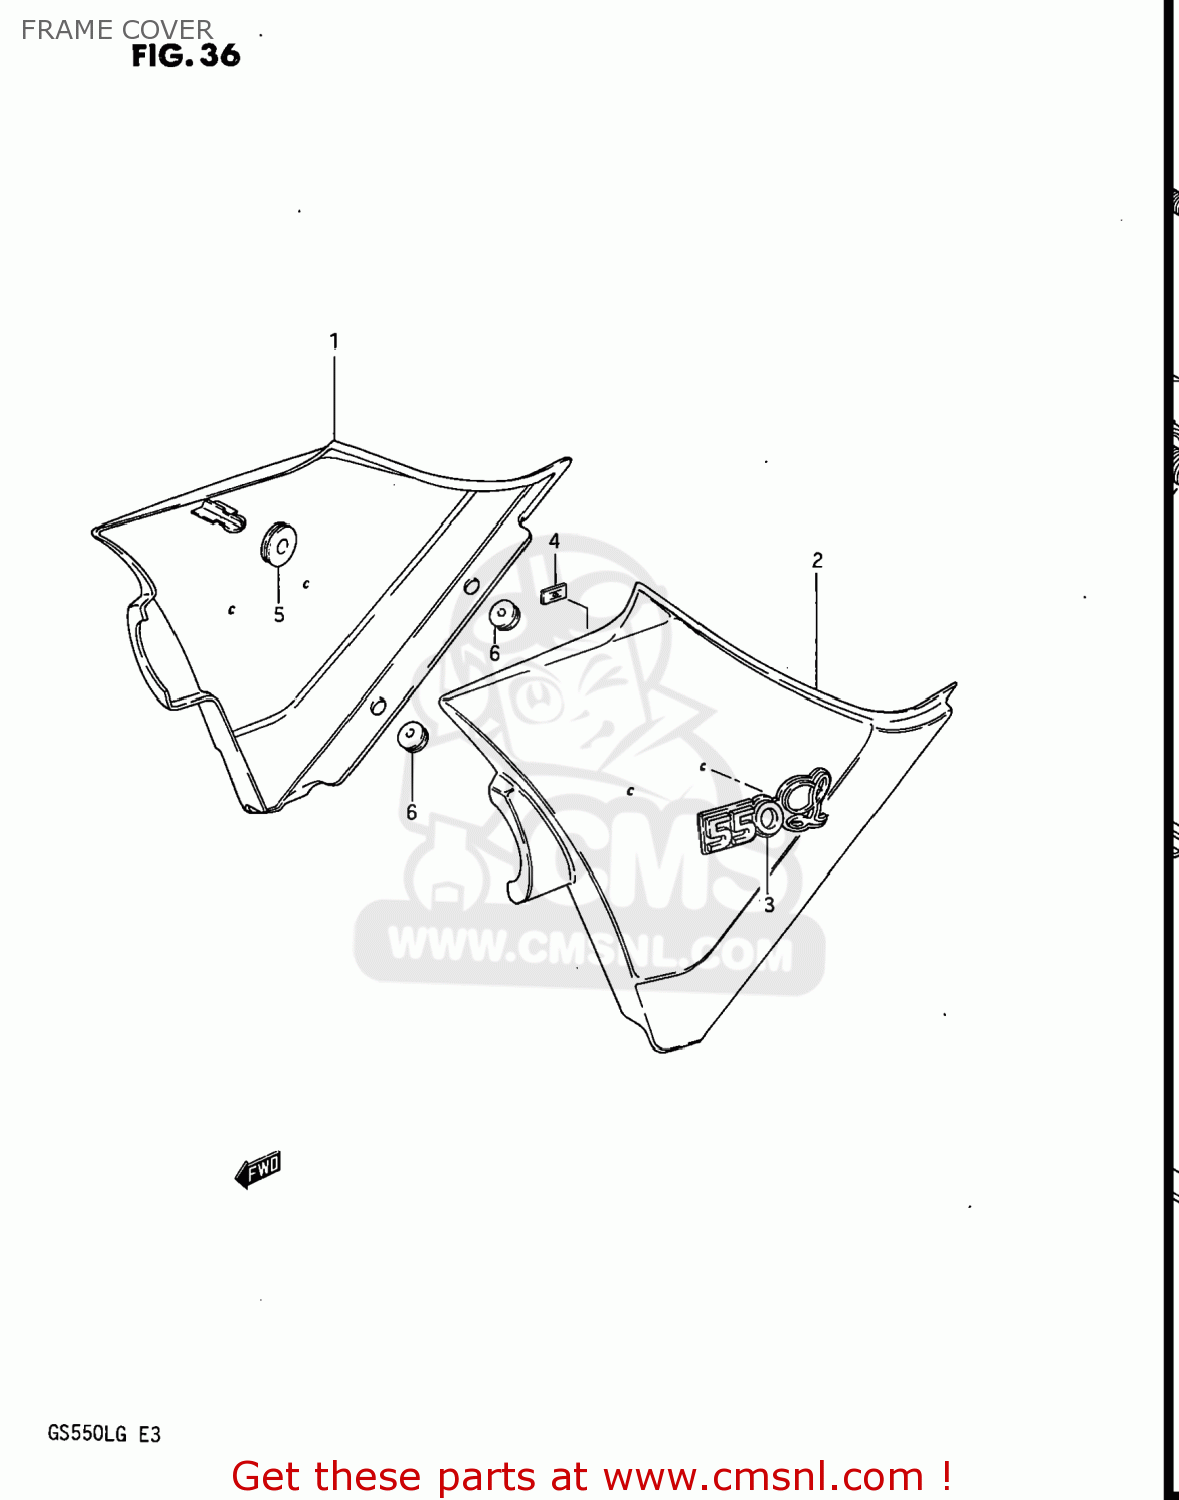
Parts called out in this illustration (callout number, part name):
1	COVER,FRAME,RIGHT
2	COVER,FRAME,LEFT
3	EMBLEM,FRAME COVER
4	NUT
5	CUSHION
6	CUSHION
